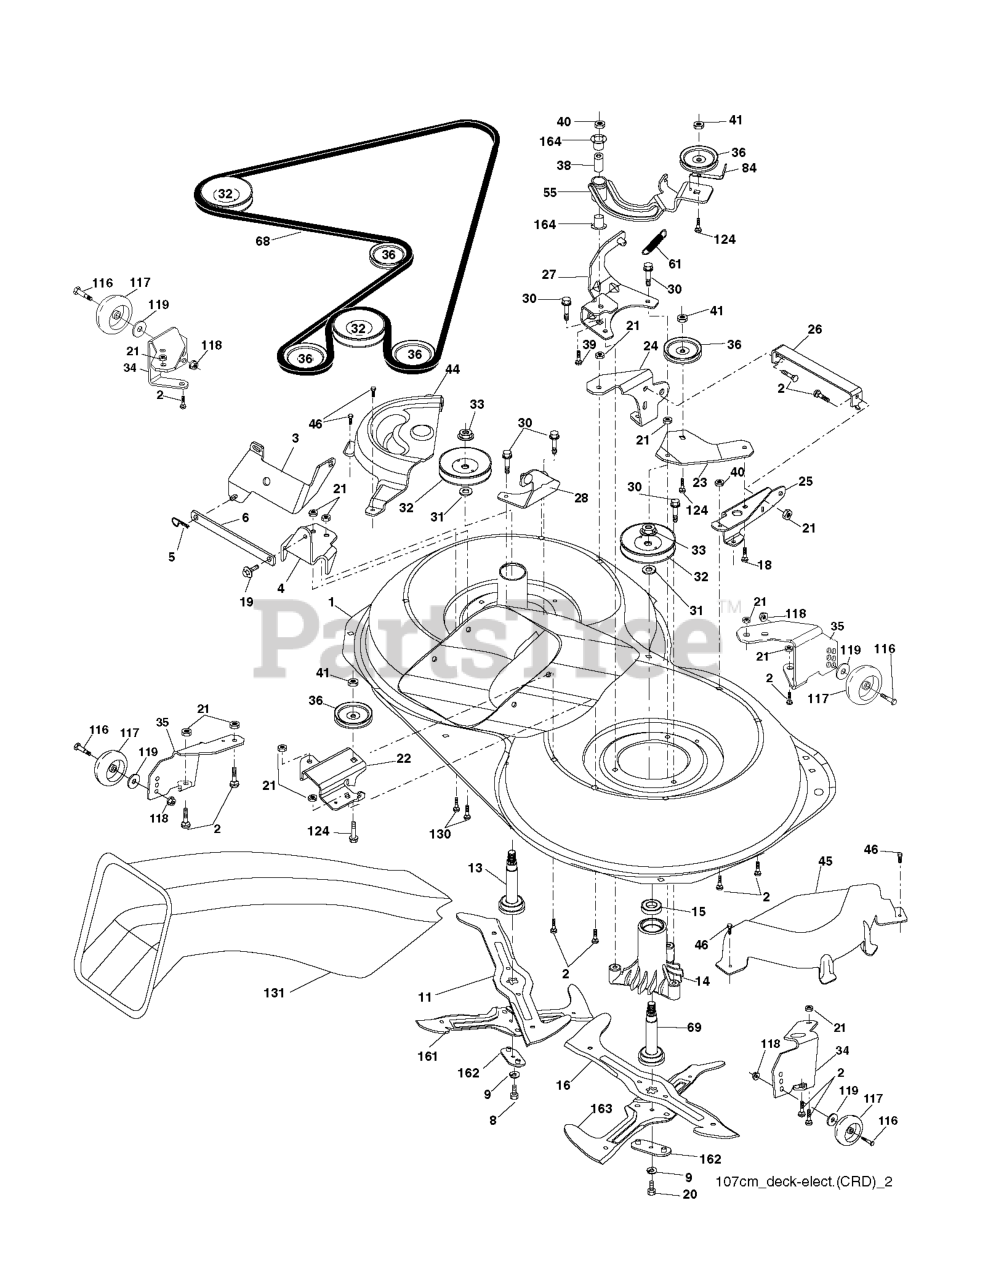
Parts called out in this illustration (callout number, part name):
1	Housing Asm. Mower 107 CRD
2	RP BOLT 5/16-18 X3/4 ZN/YEL GR
5	RETAINER-SPRNG RB
6	BAR.SWAY.92.CRD
8	BOLT.3/8-24X1.25 GR8
9	LOCKWASHER
11	BLADE.3N1.LH.CRD
13	SHAFT ASM VENT
14	HOUSING.MANDREL.VENTED (MACHD)
16	BLADE.3N1.RH.CRD
19	BOLT SHD 5/16-18
20	BOLT.3/8-24X1.25GR8. LHTHRD
21	LOCKNUT
22	BRACKET.IDLER.RR.107.CRD
24	BRACKET
25	BRACKET RF
26	SUPPORT
28	BRACKET
30	SCREW, WASHER HEAD
31	WASHER.SPACER.MANDREL
32	PULLEY.MANDREL.4.80 PD.2006
33	NUT.FLANGE.LOCK.TOP
34	BRACKET
35	BRACKET
36	PULLEY.IDLER.4.25
41	NUT LOCK FLG 3/8-16 UNC
45	COVER.MANDREL.RH.CRD
46	SCREW.1/4-20X5/8
55	ARM.IDLER.107.CRD
61	SPRING
68	HEX-BELT 107 MOWER
69	SHAFT.ASM.W/LWR.BRG.RH.THREAD
84	KEEPER, BELT IDLER
116	BOLT.SHOULDER.3/8-16X3-5/8.
117	RP WHEEL. GUAGE RALLY
118	NUT LOCK FLG 3/8-16 UNC
119	WASHER
124	BOLT.3/8-16X1.50
130	BOLT.CARR.SQNK.5/16-18UNC.X3/4
131	CHUTE BAGGER
163	BLADE.CROSS.RH.CRD.107
164	BRNG T
